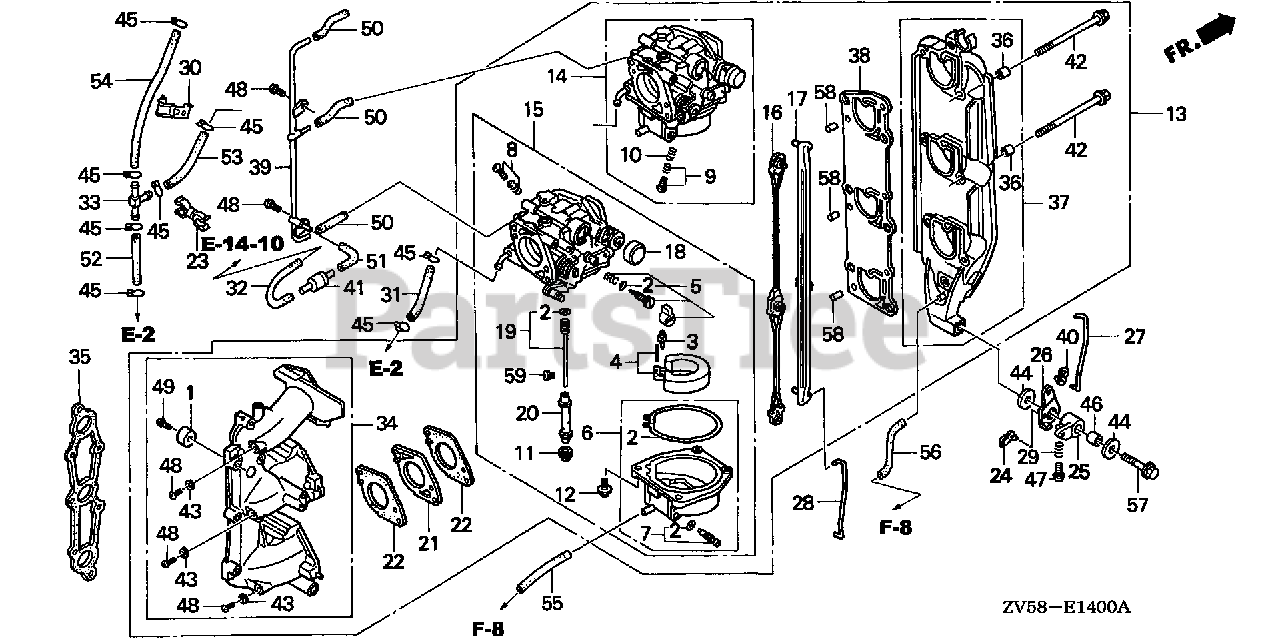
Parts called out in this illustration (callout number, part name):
1	METAL, ANODE
2	GASKET SET
3	VALVE SET, FLOAT
5	SCREW SET (CARBURETOR NO.)
6	CHAMBER SET, FLOAT
7	SCREW SET, DRAIN
10	SPRING, COMPRESSION COIL
11	SCREW, PLUG
12	SCREW-WASHER
13	CARBURETOR ASSY. (BG31B C) *NH8* (DARK GRAY)
14	CARBURETOR ASSY. (#1/#2) (CARBURETOR NO.)
15	CARBURETOR ASSY. (#3) (CARBURETOR NO.)
16	LEVER, LINK
17	LINE, CHOKE
18	CAP, CHOKE DUST
19	JET SET (#42)
20	NOZZLE, MAIN
21	INSULATOR, CARBURETOR
22	GASKET, CARBURETOR
23	CLAMP, FUEL TUBE (A)
24	JOINT, ROD
25	ARM A, CHOKE
26	ARM B, CHOKE
27	ROD, CHOKE
28	ROD, CHOKE KNOB
29	SPRING, CHOKE ARM ADJUSTING
30	CLAMP, FUEL TUBE
31	TUBE C, FUEL
32	TUBE D, FUEL
33	PIPE, THREE WAY JOINT
34	MANIFOLD, IN. *NH8* (DARK GRAY)
35	GASKET, IN. MANIFOLD
36	COLLAR, DISTANCE
37	PLATE, MUFFLER
38	GASKET, MUFFLER PLATE
39	PIPE, INSTALL
40	BUSH, LINKAGE
41	VALVE, DASHPOT CHECK
42	BOLT, FLANGE (6X97)
43	WASHER, SEALING (5MM)
44	WASHER, PLAIN (6MM)
45	CLIP, TUBE (B10)
46	COLLAR, DISTANCE (6.5X10.5X16)
47	SCREW, PAN (4X16)
48	SCREW, PAN (5X10)
49	SCREW, PAN (6X18)
50	BULK HOSE, FUEL (3.5X3000) (3.5X45)
51	BULK HOSE, FUEL (3.5X3000) (3.5X60)
52	BULK HOSE, FUEL (5.5X3000) (5.3X65)
53	BULK HOSE, FUEL (5.5X3000) (5.3X110)
54	BULK HOSE, FUEL (5.5X3000) (5.3X170)
55	BULK HOSE, VINYL (3.5X6.5X8000) (3.5X6.5X160)
56	BULK HOSE, VINYL (3.5X6.5X8000) (3.5X6.5X200)
57	BOLT, FLANGE (6X28)
58	ROLLER (6X15)
59	JET, MAIN (#125)
59	JET, MAIN (#128)
59	JET, MAIN (#130)
